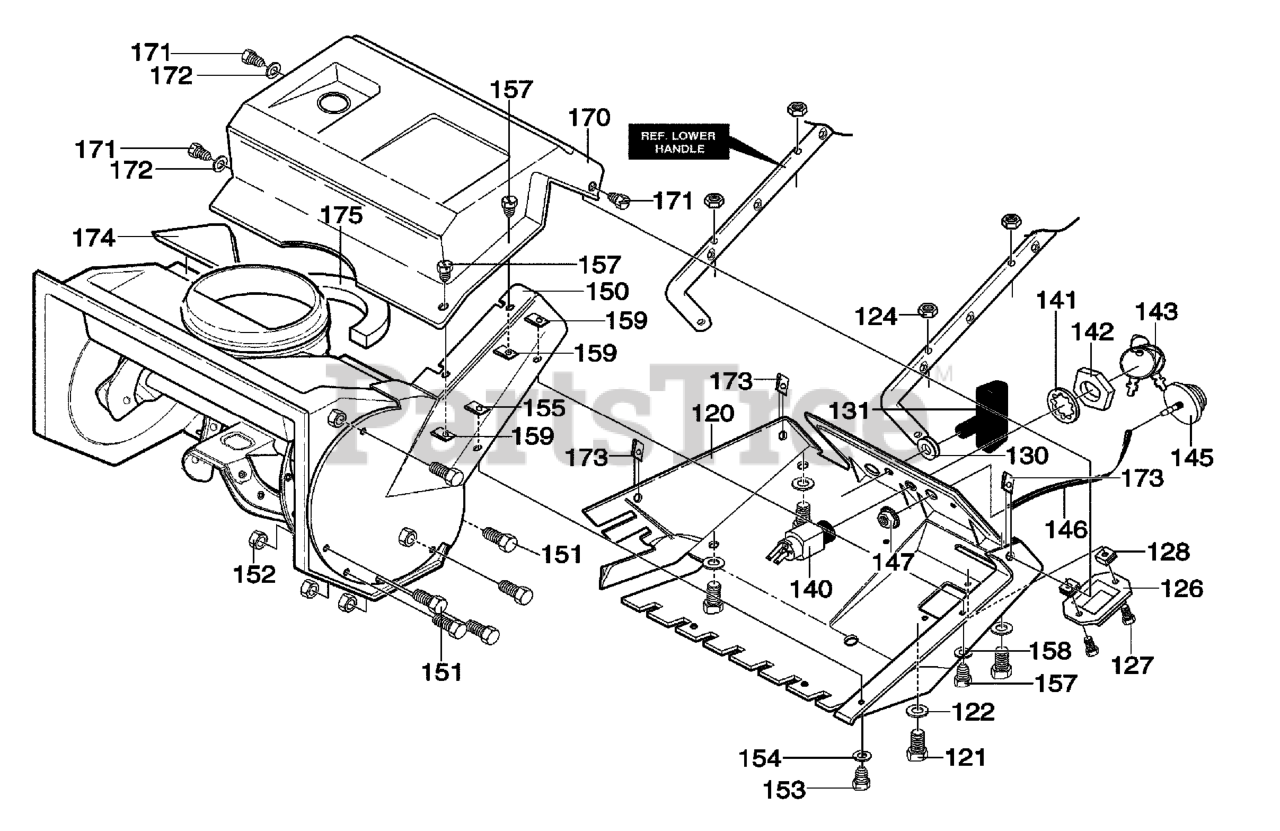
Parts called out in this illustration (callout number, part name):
120	COVER, BOTTOM
121	SCREW, 1/4-20X1.25
122	WASHER, FLAT
124	NUT, 1/4-20
126	COVER, CARB
127	SCREW, 1/4-14X.75
128	NUT, 1/4-10 SPEED J TYPE
130	GROMMET & WASHER, ROPE GUIDE
131	KNOB, STAND TEE
140	SWITCH, IGNITION
141	WSHER
142	NUT, 5/8-32 ACC
143	2 KEYS & RING
145	PRIMER, ENGINE
146	HOSE, PRIMER
147	NUT, 1/4-20
150	COVER, BELT
151	SCREW, 10-24X.50
152	NUT, #10-24
153	SCREW, 1/4-20X.50
154	WASHER, FLAT
155	NUT, 1/4-20
157	SCREW, 1/4-14X.75
158	WASHER, FLAT
159	NUT, 1/4-20
170	COVER, TOP
171	SCREW, 1/4-14X.75
173	NUT, 1/4-10
174	SEAL, STRIP
175	SEAL, STRIP CHUTE & GAS SEAL
